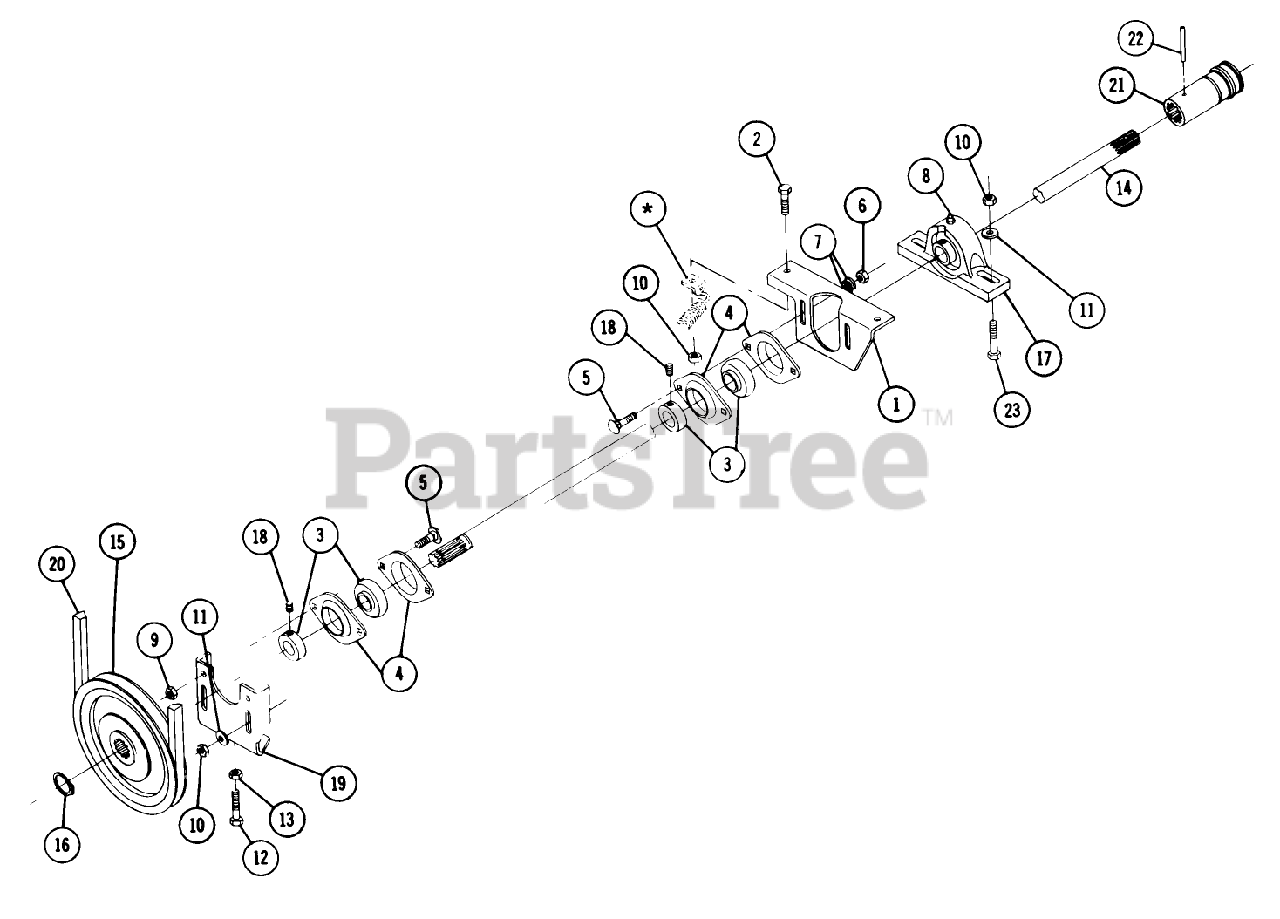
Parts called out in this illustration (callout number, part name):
2	Bolt 3/8-16 x 3/4
5	Bolt-Car. 5/16-18 x 1
6	Nut-Nylok
7	Washer
9	Nut-Nylok
11	Washer
12	Bolt Hex 3/8-16 x 1 1/2
13	3/8-16 Jam Nut
18	Set Screw 1/4-28 x 1/4
22	SPIROL PIN
23	Bolt, 3/8-16 x 1/2
